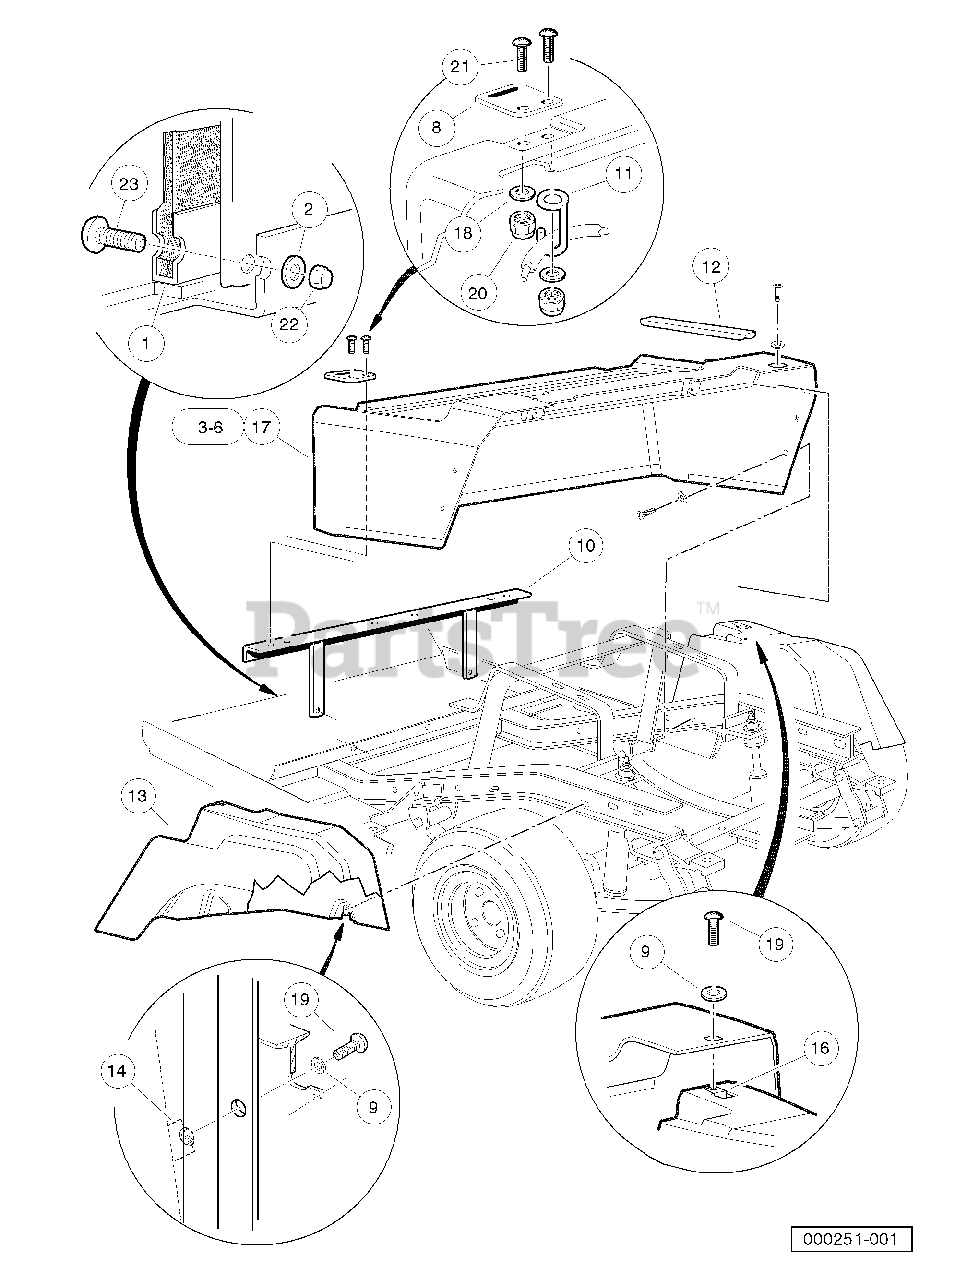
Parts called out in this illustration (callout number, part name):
1	Body Kick Plate
2	Washer, 1/4" Type B Flat
3	Body, Rear, Gas, Red
4	Body, Rear, Gas, Green
5	Body, Rear, Gas, Classic Blue
6	Body, Rear, Gas, Olive Green
7	Body Assembly
8	Body, Hinge Plate
9	Washer, 1/4" Type B Flat
10	Body Support Front
11	Cable Retainer
13	Fender, Driver Side
14	U-N ut, 1 /4-20
15	Fender, Passenger Side
16	U-N ut, 1 /4-20
17	Body, Rear, Gas, Orange
18	Washer, 1/4 Type A Narrow Flat
19	Screw, 1/4-20 X 0.75 Hex-Head Cap
20	Locknut, 1/4-20 Nylon Insert
21	Screw, 1/4-20 X 1.0 Truss-Head Machine
22	Locknut, 1/4-20 Nylon Insert
23	Screw, 1/4-20 X 1.0 Truss-Head Machine
